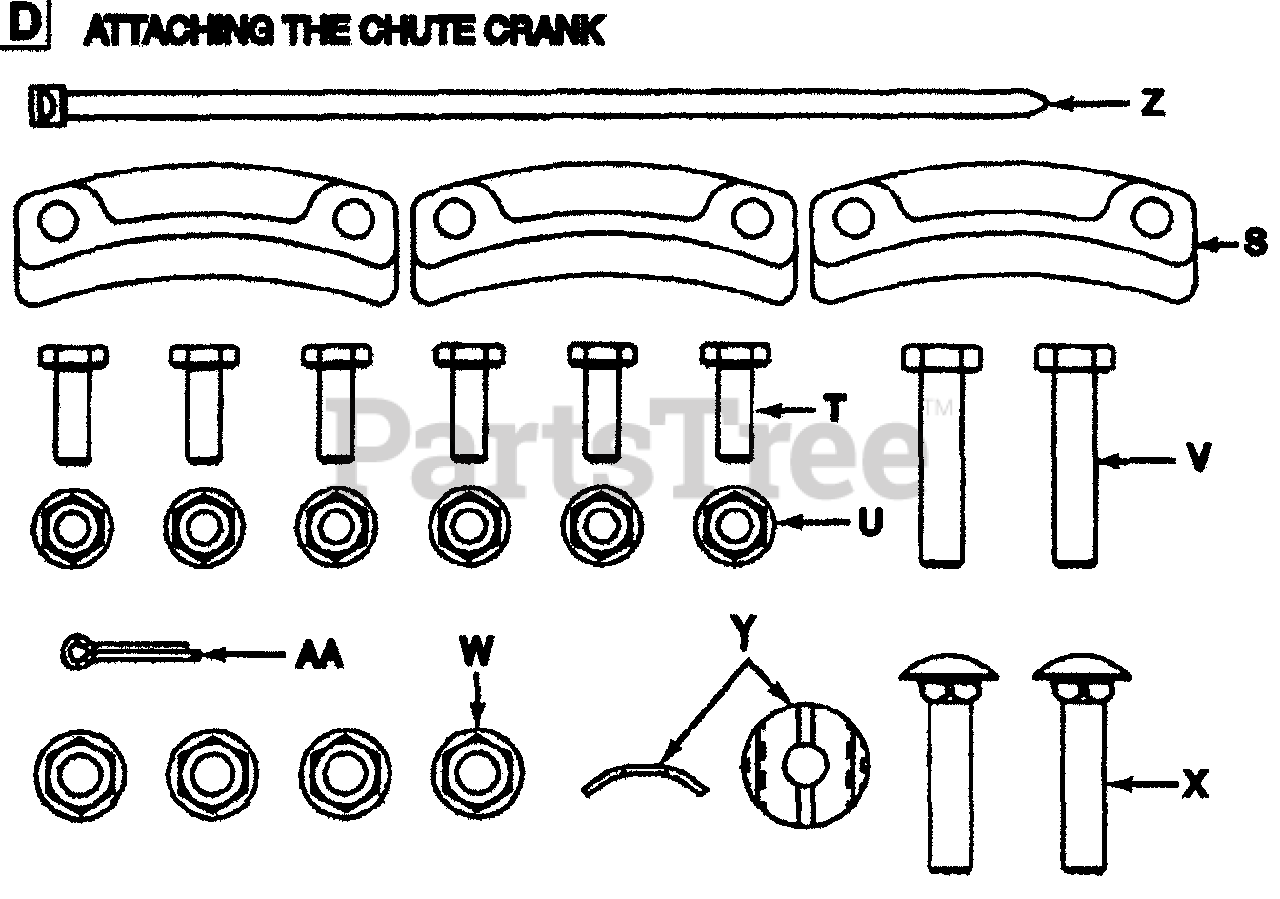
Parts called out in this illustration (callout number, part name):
S	Chute Flange Keepers
T	Hex Bolts 1/4-20 x .75" Long
U	Hex Lock Nuts 1/4-20 Thread
V	Hex Bolts 5/16-18 x 1.5" Long
W	Hex Flange Lock Nuts 5/16-18 Thread
X	Carr. Bolts 5/16-18 x 1.5" Long
Y	Saddle Washers.32" I.D. x.83" O.D.
AA	Cotter Pin .75" Long
